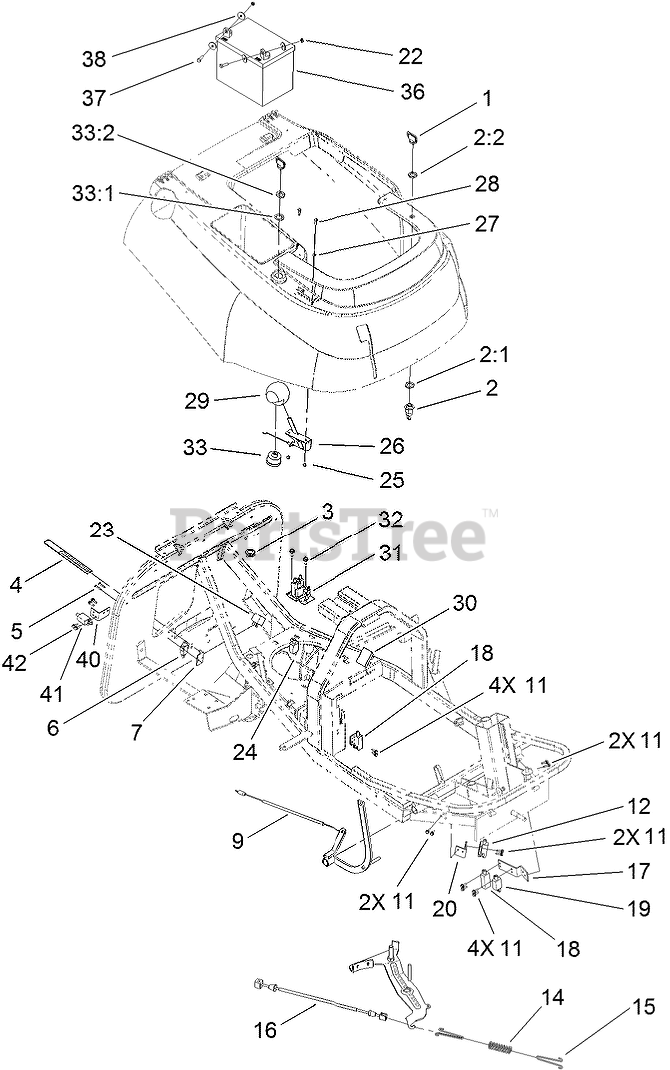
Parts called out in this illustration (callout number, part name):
1	KEY-IGNITION
2	STARTER SWITCH ASM
2:1	WASHER-TOOTH, INTERNAL
2:2	NUT-HH
3	Grommet
4	Lever-Bag Fill
6	Switch
7	Clamp-Bag Fill
9	CABLE-BRAKE
11	SCREW-HH, TAP
12	SWITCH-DOUBLE, POLE
14	Spring-Compression
15	Hook-Spring
17	Bracket-Switch
18	SWITCH-INTERLOCK
19	SWITCH-POLE, SINGLE
20	Bracket-Switch
22	NUT-HEX
23	RELAY
24	SWITCH-POLE, SINGLE
25	NUT-LOCK
26	Throttle Cable ASM
27	WASHER
28	SCREW-HH
30	MODULE
31	SOLENOID
32	SCREW-HHF, TAP
33	Key Switch ASM
33:1	WASHER-TOOTH, INTERNAL
33:2	NUT-HH
36	BATTERY-155 CCA
37	SCREW-HH
38	Washer-Flat
40	BRACKET-COLLECTOR, SWITCH
41	SWITCH-POLE, SINGLE
42	SCREW-HH, TAP
